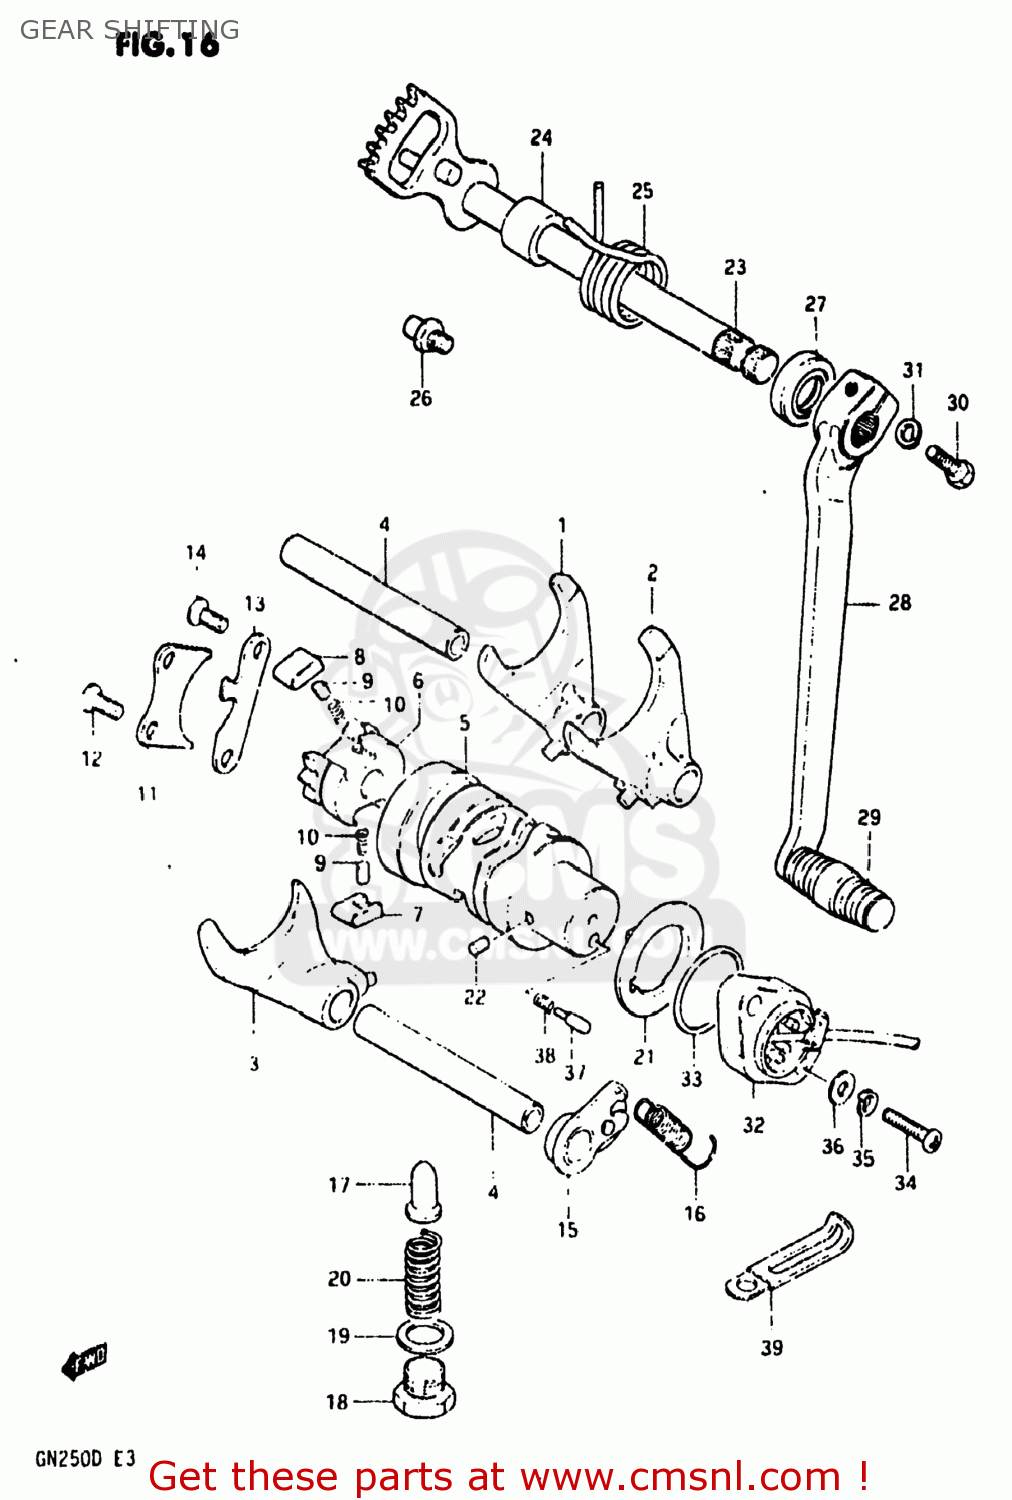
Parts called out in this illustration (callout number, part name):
1	FORK,GEAR SHIFT NO.1
2	FORK,GEAR SHIFT
3	FORK,GEAR SHIFT NO.3
4	SHAFT,GEAR SHIFT FORK
5	CAM,GEAR SHIFT
6	RETAINER,GEAR SHIFT CAM
7	PAWL,GEAR SHIFT NO.1
8	PAWL,GEAR SHIFT NO.2
9	PIN(5X8)
10	SPRING
11	LIFTER,GEAR SHIFT PAWL
12	SCREW
13	GUIDE,GEAR SHIFT CAM
14	SCREW
15	STOPPER,GEAR SHIFT CAM
16	SPRING
17	STOPPER,GEAR SHIFT CAM NO.2
18	PLUG (14X12)
19	GASKET(14X19.2X2) (NAS)
20	SPRING
21	PLATE,GEAR SHIFT CAM STOPPER
22	PIN 4X6
23	SHAFT,GEAR SHIFT
24	SPACER(12X20X15.3)
25	SPRING
26	STOPPER,GEAR SHIFT CAM
27	OIL SEAL
28	LEVER ASSY,GEAR SHIFT
29	RUBBER,GEAR SHIFT PEDAL
30	BOLT
31	LOCK WASHER
32	BASE ASSEMBLY,NEUTRAL SWITCH TERMINAL
33	O-RING (D:2.4 ID:26.2)
34	SCREW 5X20
35	LOCK WASHER
36	WASHER
37	PIN(5X15.5)
38	SPRING
39	CLAMP
